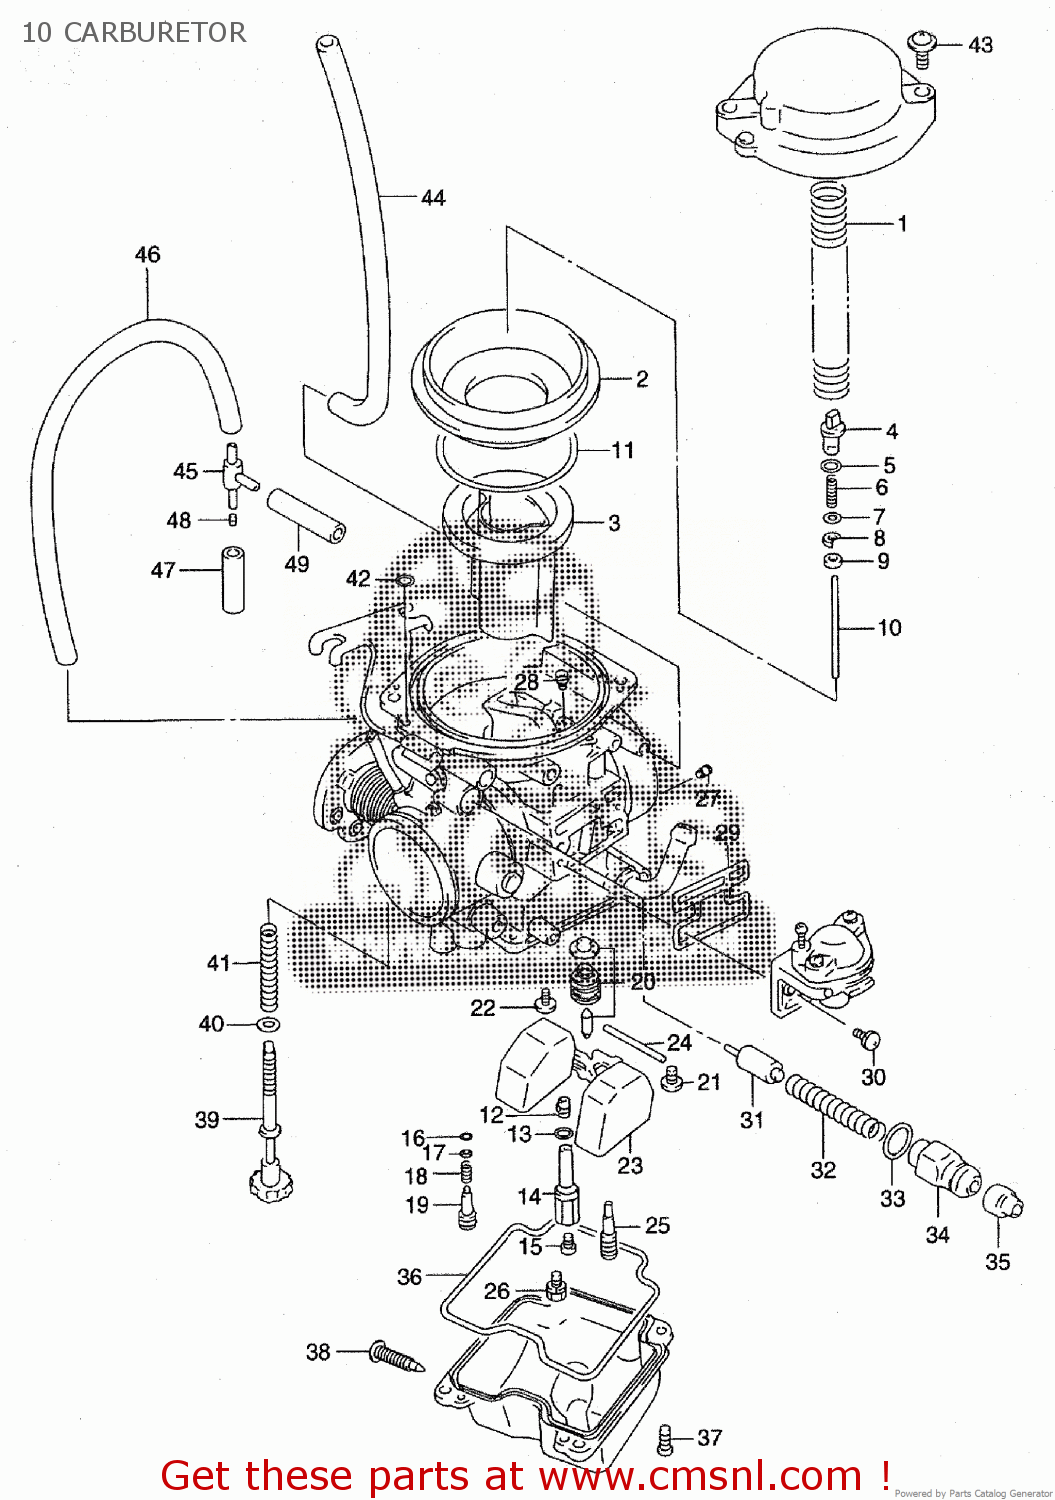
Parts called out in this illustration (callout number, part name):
1	SPRING
2	DIAPHRAGM
3	VALVE,PISTON
4	HOLDER
5	O RING(D:1.9,ID:4.8)
6	SPRING
7	WASHER
8	E RING,MULTIPLE JET NOZZLE
9	RING
11	RING
12	JET,NEEDLE(P-0)
13	O RING
14	HOLDER,JET
15	JET,MAIN(122.5)
16	O RING,PILOT AIR SCREW
17	WASHER
18	SPRING,THROTTLE SCREW
19	ADJUSTER
20	VALVE ASSY,NEEDLE(ID:2.3)
21	SCREW
22	SCREW
23	FLOAT ASSY
24	PIN,FLOAT
25	JET,PILOT(22.5)
26	JET,MAIN(57.5)
28	JET,PILOT(155)
29	O RING
31	PLUNGER,STARTER
32	SPRING
33	O RING
34	HOLDER,GUIDE
35	CAP
36	GASKET (NAS)
37	SCREW
38	PLUG,DRAIN
39	SCREW,ADJUST
40	PACKING (NAS)
41	SPRING
42	O RING
43	SCREW
44	HOSE
45	NIPPLE
46	HOSE
47	HOSE(L:425)
49	HOSE(5X10X600)
